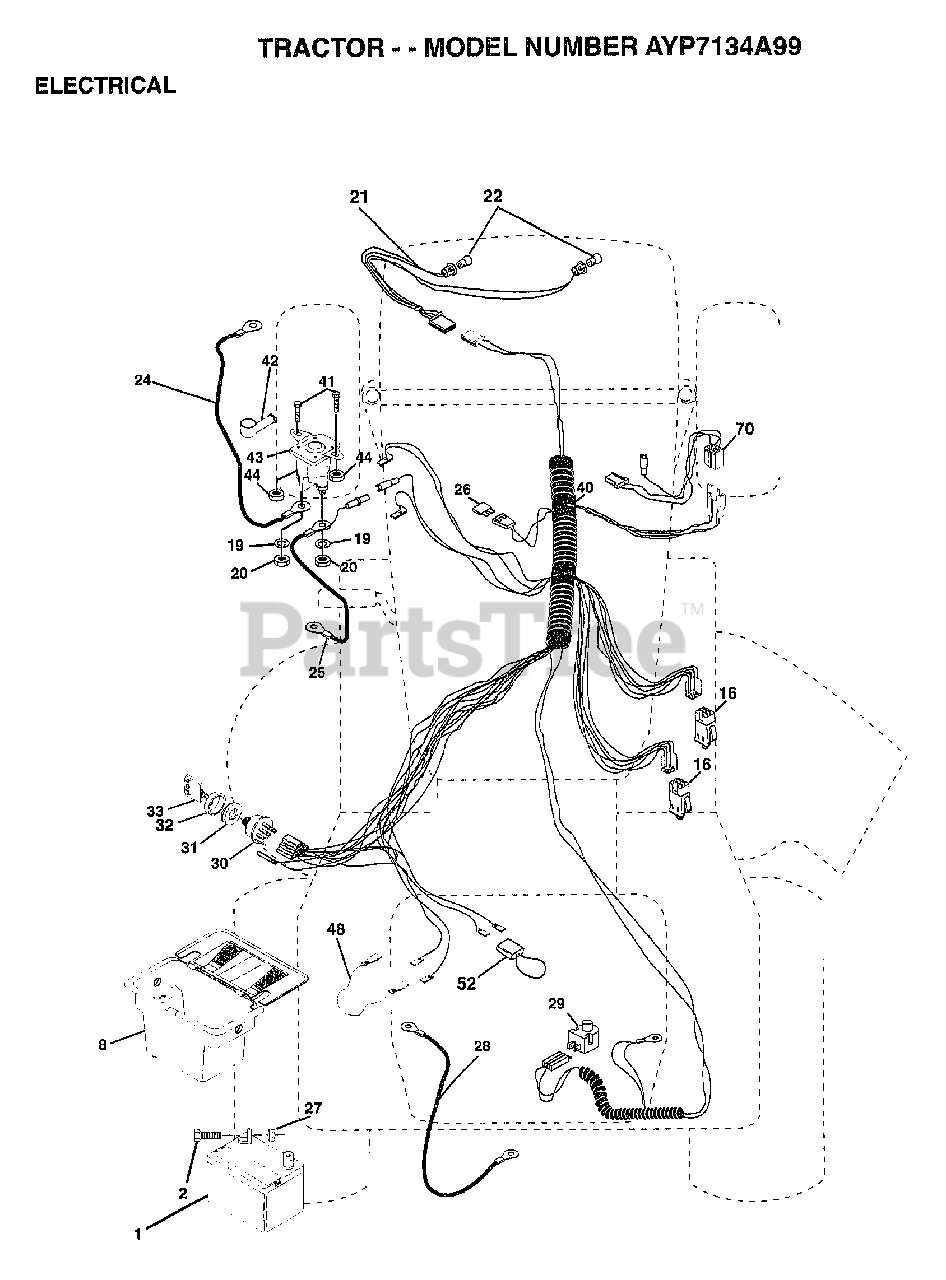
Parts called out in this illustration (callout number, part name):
2	BOLT LT
8	"CASE,BATTERY.MECH"
16	SWITCH INTERLOCK
20	NUT
21	HARNESS
22	HEADLAMP BULB
24	"CABLE T, BATTERY"
25	CABLE.BTRY.6GA.RD
26	FUSE.15 AMP
27	NUT
28	CABLE T
29	SWITCH SEAT
30	SWITCH IGN 4POS
31	NUT IGNITION
32	COVER KEY SWITCH
33	KEY
40	HARNESS.IGNITION
41	BOLT HXHD FIN
44	NUT HXKEP 1/4X20
48	ADAPTER AMMETER
52	PROTECTION LOOP
70	HARNESS.ENGINE
